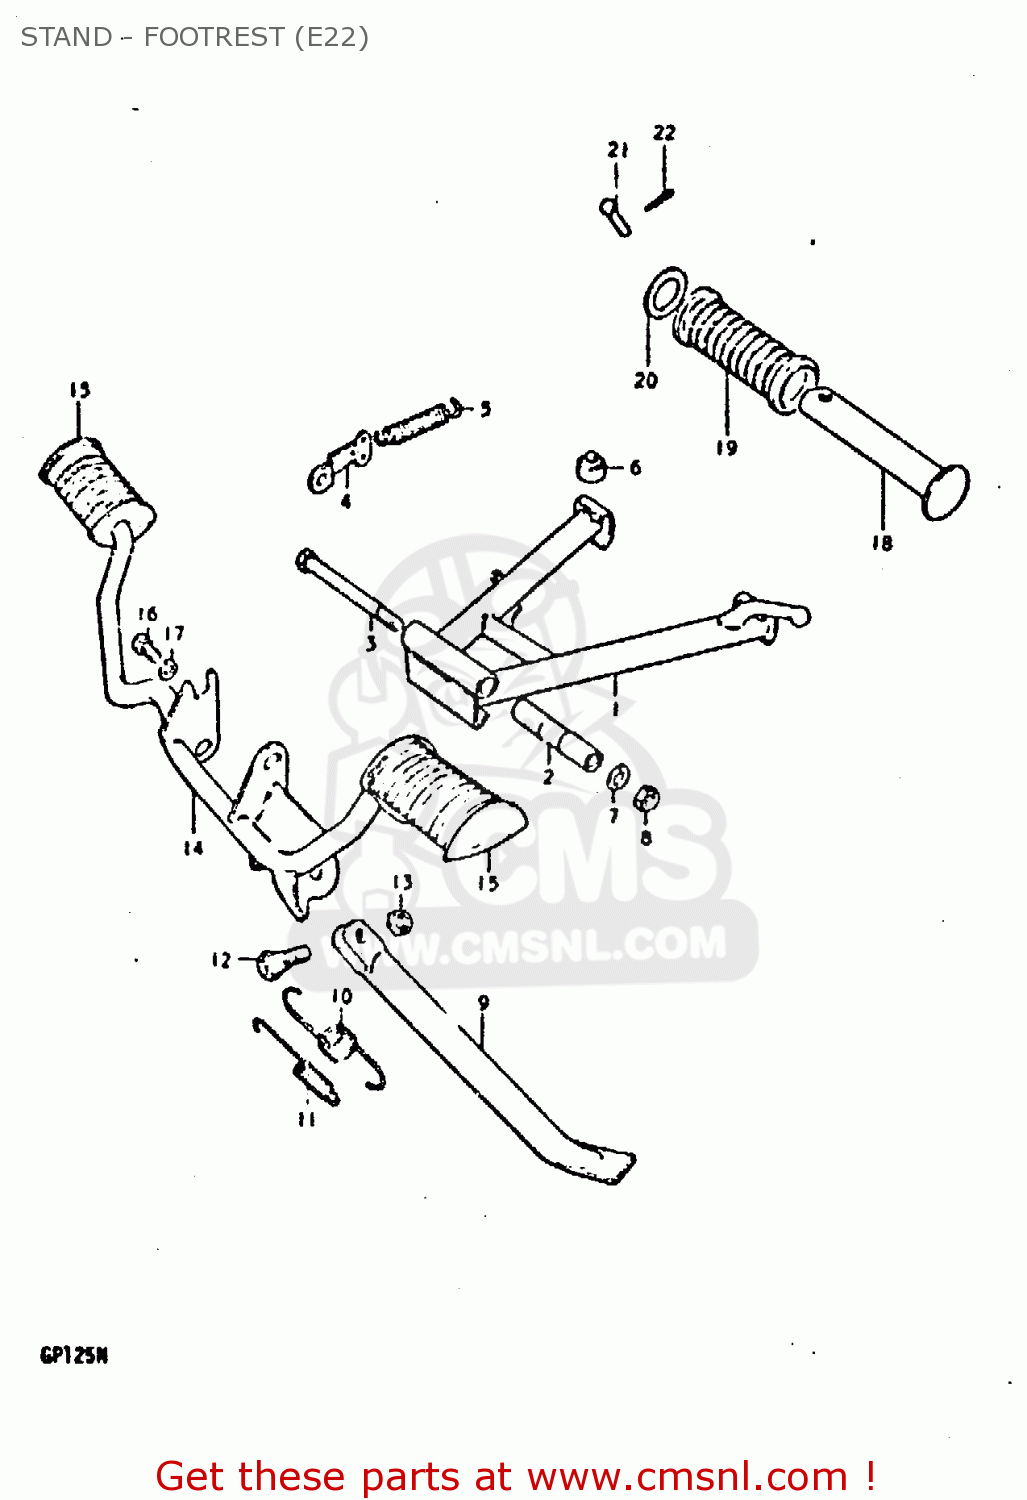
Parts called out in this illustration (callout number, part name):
1	STAND, CENTER
2	SPACER
3	BOLT(10X110)
4	HOOK
5	SPRING
6	CUSHION
7	LOCK WASHER
8	NUT
9	STAND, PROP
10	SPRING, OUTER
11	SPRING
12	BOLT(10X28)
13	NUT
14	BAR, FRONT FOOTREST
15	RUBBER,FR FOOTREST
16	BOLT
17	LOCK WASHER
18	BAR,FOOTREST RUBBER
19	RUBBER,PILLION FOOTREST
20	WASHER (19.5X32X2)
21	PIN
22	PIN 20X20
